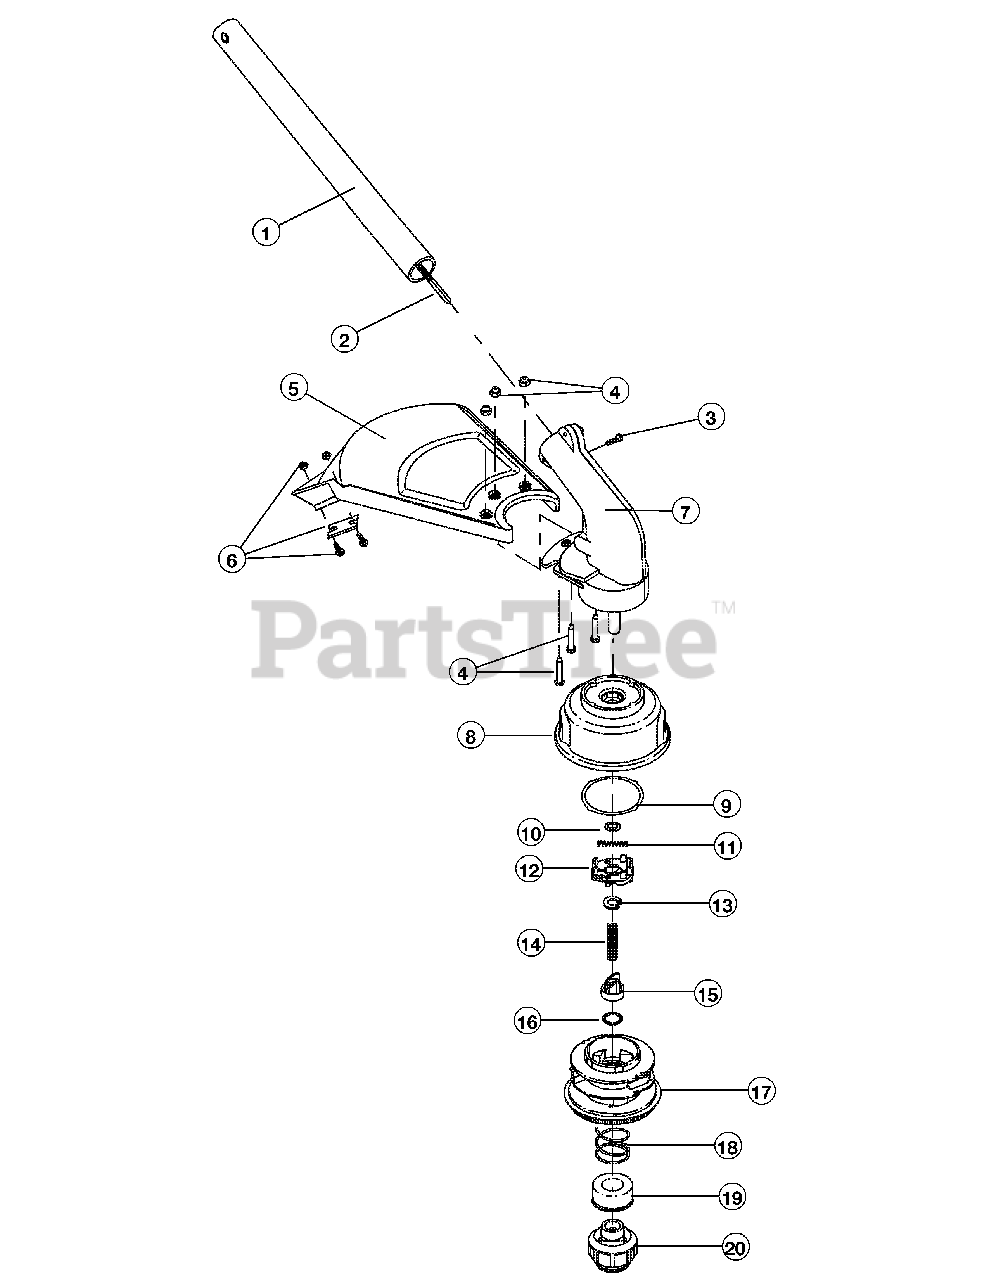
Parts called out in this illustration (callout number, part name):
1	Lower Drive Shaft Housing Assembly
2	Lower Flexible Drive Shaft
3	Anti-Rotation Screw
4	Shield Mounting Hardware
5	Shield and Blade Assembly (includes 6)
6	Blade Assembly
7	Gearbox Assembly (includes 8-20)
8	Outer Spool Assembly (includes 10)
9	Thrust Washer
10	Retaining Ring
11	Small Spring
17	Inner Reel
18	Large Spring
20	Bump Head Knob Assembly (includes 18 & 19)
